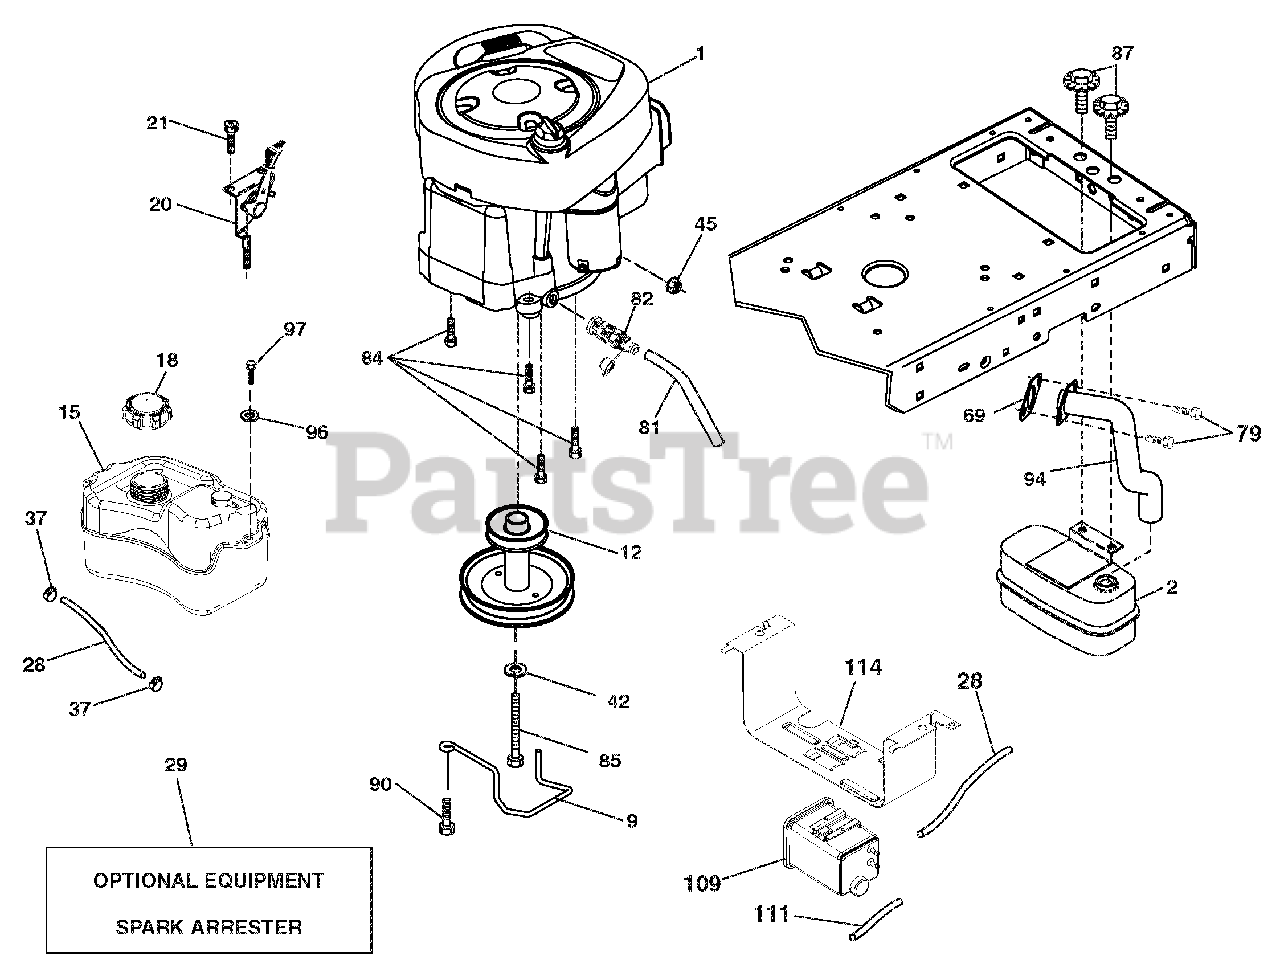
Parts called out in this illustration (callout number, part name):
1	ENGINE B&S MODEL NO. 331977-0005-G1 (581882001)(ORDER PARTS FROM ENGINE MANUFACTURER.)
2	MUFFLER.SINGLE.CYL.KOHL.COURAG
9	KEEPER BELT ENGINE
12	PULLEY.ENGINE
15	TANK ASM.FUEL.1.50.CARB.CA.SVC
18	CAP FUEL
20	CONTROL THROTTLE/CHOKE
28	LINE.FUEL.64"REAR.EMIS.CA.LP
29	KIT.SPARK ARRESTOR(392390 B&S)
37	CLAMP.HOSE.BLK.
42	WASHER.LOCK.HVY HLCL.SPR.7/16
45	Nut, Keps Hex 1/4-20 unc
69	Gasket Eng 1 313 Id Tin Plated
79	SCREW.SOCKET HD.5/16-18 X .75
81	TUBE.DRAIN.OIL.EASY
82	VALVE OIL DRAIN
84	Screw 3/8-16 x <
85	BOLT.HEX.7/16-20X4XGR5-1.5THR.
87	BOLT.5/16-18UNCX3/4 W/SEMS.BLK
90	SCREW.3/8-16X1.SMGML.TAP/R.BLK
94	EXHAUST TUBE
96	WASHER.9/32 X 7/8 X 16GA.
97	SCREW.HEXWSH.THDROL.1/4-20X3/4
109	CANISTER.CARBON.FILTER ASM.TEX
111	PURGE.LINE.CARB
114	CRADLE.CANISTER.CARBON
